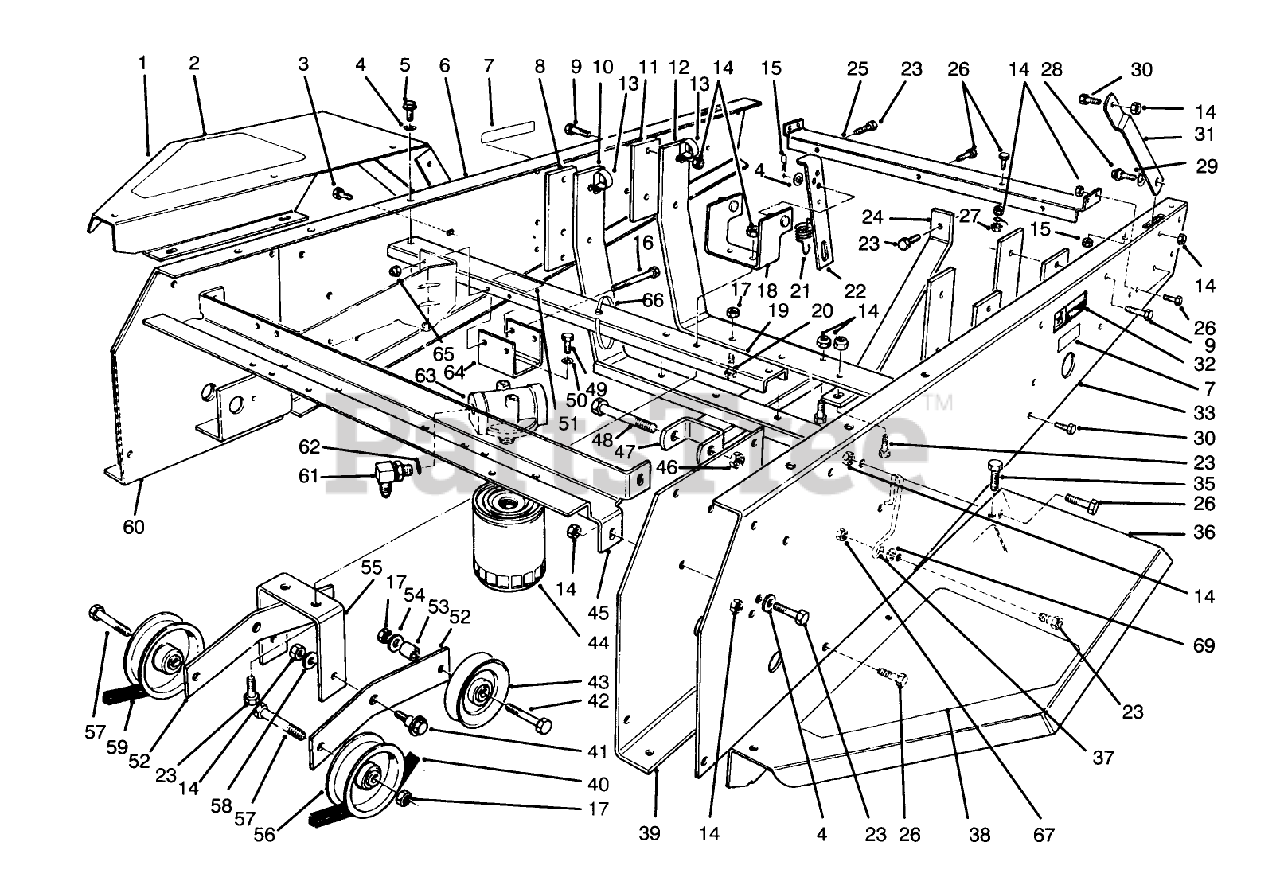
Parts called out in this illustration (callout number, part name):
1	Fender R.H
2	RH FENDER PAD
3	SCREW-HHF
4	WASHER-PLAIN
5	SCREW-HWHTF
6	Channel-Side R.H.
7	DECAL-WARNING
8	FRONT ENG PLATE
9	SCREW-HH
10	Mount-Engine
11	REAR ENG PLATE
12	Mount-Engine
14	NUT-LOCK, NI
15	PIN-COTTER
16	SCREW-HH
17	NUT-LOCK, NI
18	Anchor-Spring
19	MIDDLE CHANNEL WA B
20	SCREW-HH
21	IDLER SPRING
22	IDLER ANCHOR LINK
23	SCREW-HH
24	Bar-Tension
25	Support-Shield
26	SCREW-HH
27	NUT-KEPS
28	SCREW-SHOULDER
29	WASHER-SPRING
30	SCREW-HH
31	Stop-Hood Lower
32	DECAL-HOT
33	Channel-Side LH.
35	SCREW-HHFTF
36	Fender L.H.
37	BELT GUIDE
38	LH FENDER PAD
39	Axle Stand-LH.
40	V-BELT, JACKSHAFT
41	SCREW-SHOULDER
42	SCREW-HH
43	PULLEY
44	FILTER-OIL, TRANSMISSION
45	Channel-Front
46	NUT-LOCK
47	Mount-Cylinder
48	SCREW-HH
49	SCREW-HH
50	WASHER-LOCK
51	DECAL-OIL
52	IDLER LEVER
53	SPACER-WEIGHT
54	WASHER-FLAT
55	IDLER MT BRKT
56	PULLEY
57	SCREW-HH
58	WASHER
59	V-BELT, TRACTION
60	Axle Stand R.H.
61	FITTING-ELBOW, 90
62	O-RING
63	FILTER HD ASM
64	BRACKET - FILTER HEAD
65	NUT-LOCK, NI
66	TIE-CABLE
67	NUT-HF
69	WASHER-LOCK
